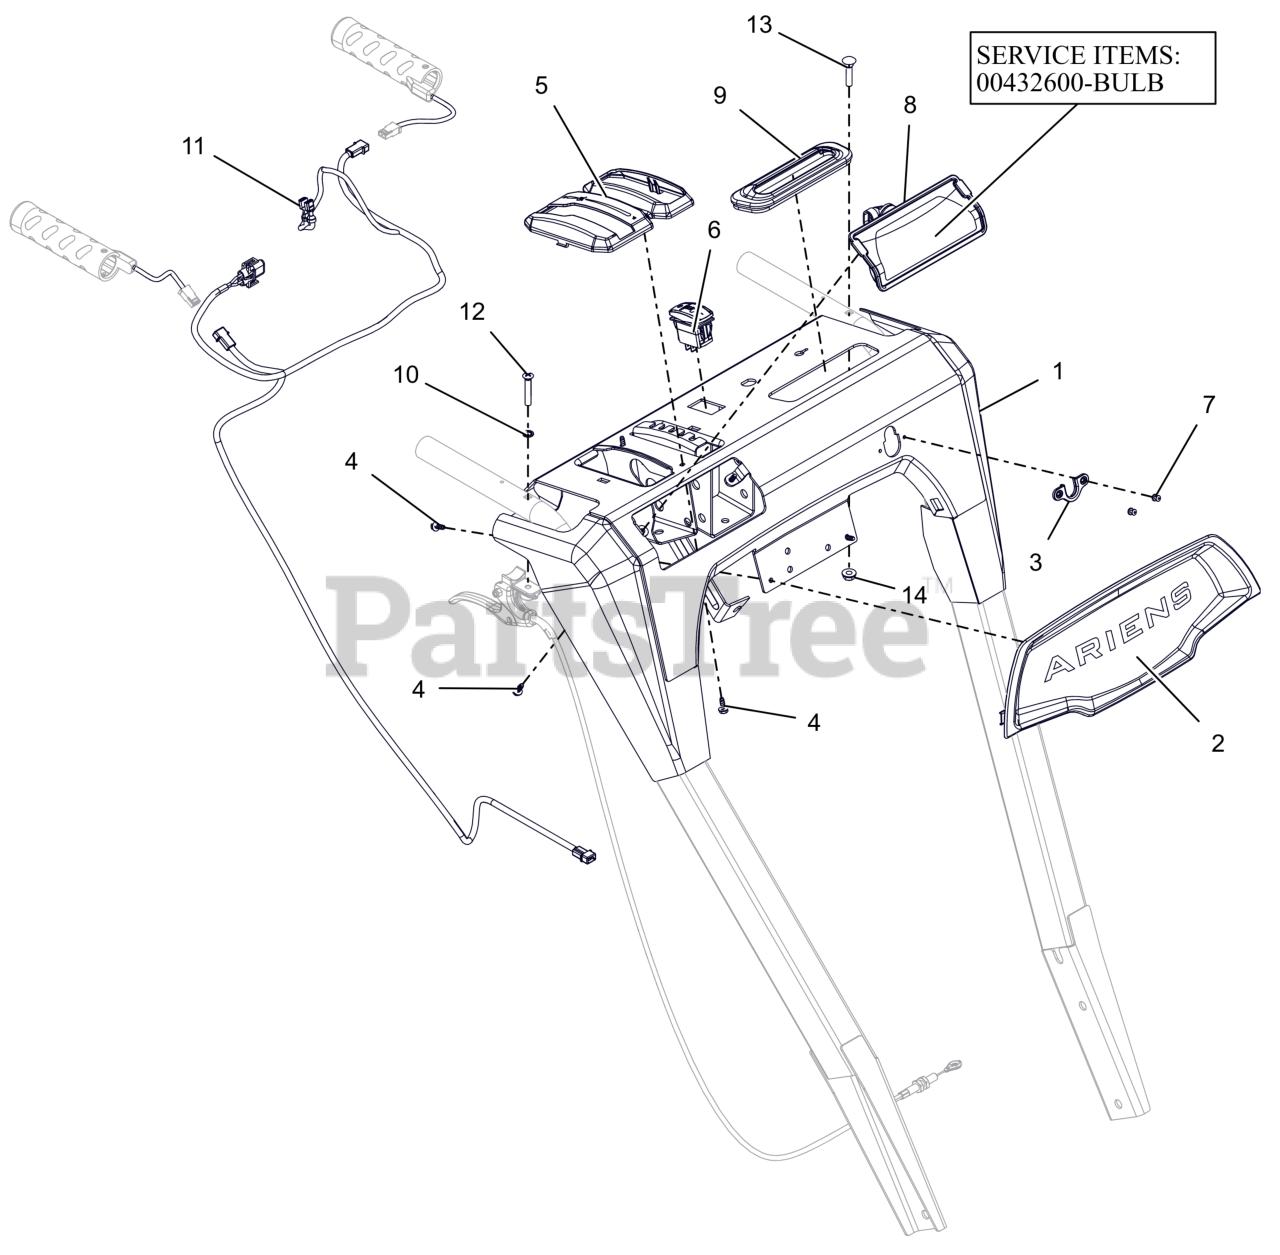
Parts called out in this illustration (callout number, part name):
1	PANEL, DASH-HYDROTRACK W/DECAL
2	BEZEL, DASH - ARIENS LG DASH
3	GROMMET, CABLE, QUICK TURN 2
4	SCR, PLASTIC #10X.50
5	BEZEL, SHIFT - HYDRO SNOW
6	SWITCH,ROCKER SPST-ON/OFF
7	RVT-POP #43 .125X.313 STL ZINC
8	HEADLIGHT ASY, HALO 20W 2SHOT
8	BULB, LIGHT-HALOGEN 20W
9	GROMMET, BOOT, QUICK TURN
10	WSHR-LK-INT .250 TH TYA
11	HARNESS, LIGHT & WARMER
12	SCR,OVAL .25-20X1.50 ZCC
13	BLT-RDHDXLSQNK.25-20X1.25 G5ZC
14	NUT-LK-CTR-FLG .25-20 ZC120
